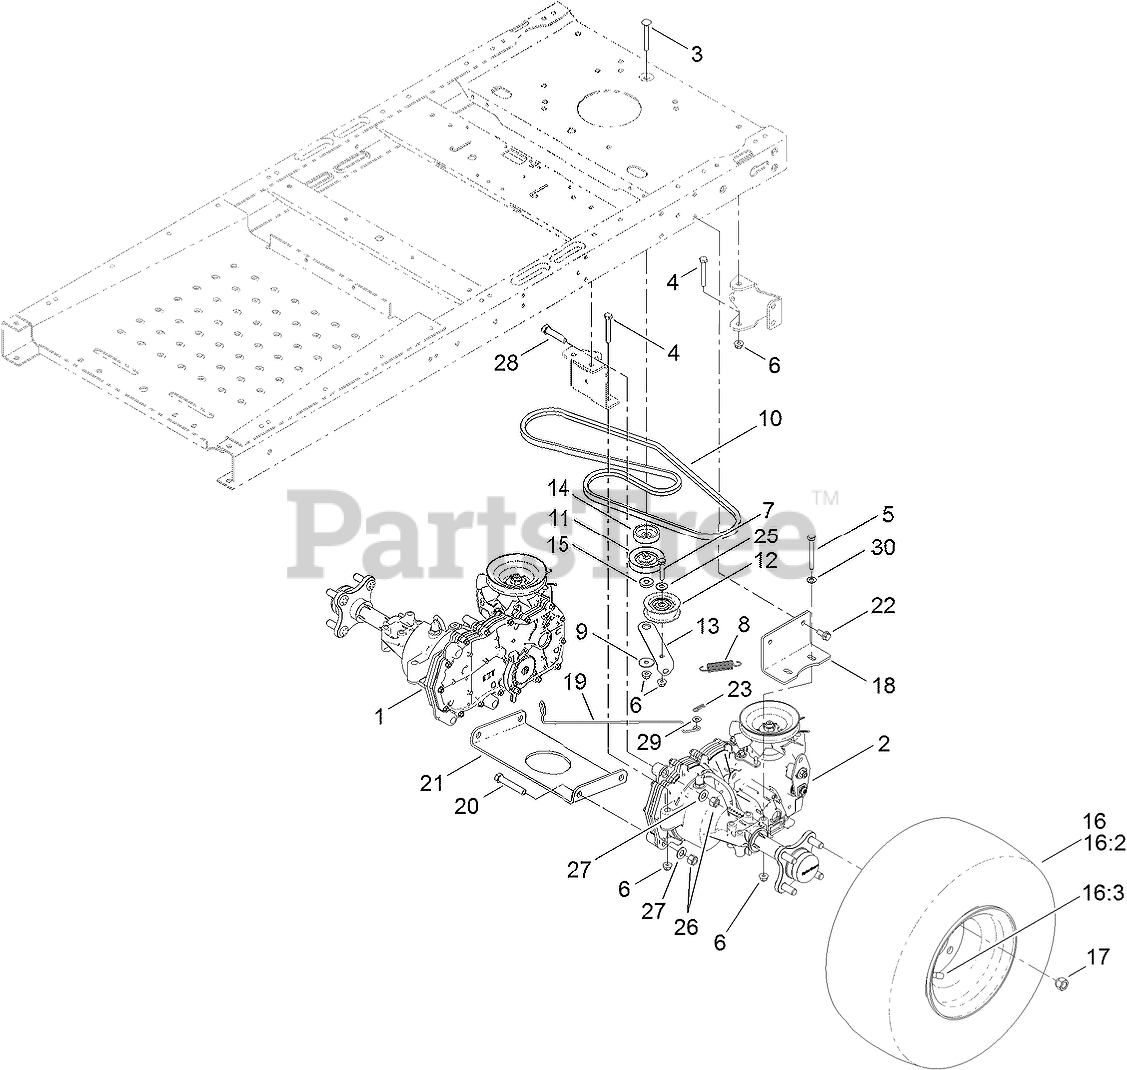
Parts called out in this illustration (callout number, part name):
1	RH HYDRO TRANSAXLE ASM
2	LH HYDRO TRANSAXLE ASM
3	SCREW-CARR
4	SCREW-HH
5	SCREW-HH
6	NUT-HF, NI
7	SCREW-HH
8	SPRING-RETURN, PEDAL
9	WASHER-PIVOT
10	V-BELT
11	PULLEY-IDLER
12	PULLEY-IDLER
13	ARM-IDLER
14	SPACER
15	SPACER-ARM, IDLER
16	4 PLY WHEEL AND TIRE ASM
16:2	TIRE-4 PLY
16:3	STEM-VALVE
17	NUT-LUG
18	MOUNT-HYDRO
19	ROD-BYPASS
20	SCREW-HH
21	PLATE-CROSS, HYDRO
22	SCREW-HHF
23	PIN-COTTER
25	WASHER-FLAT
26	NUT-LOCK, NI
27	WASHER-FLAT
28	SCREW-HH
29	WASHER-FLAT
30	WASHER-PLAIN
